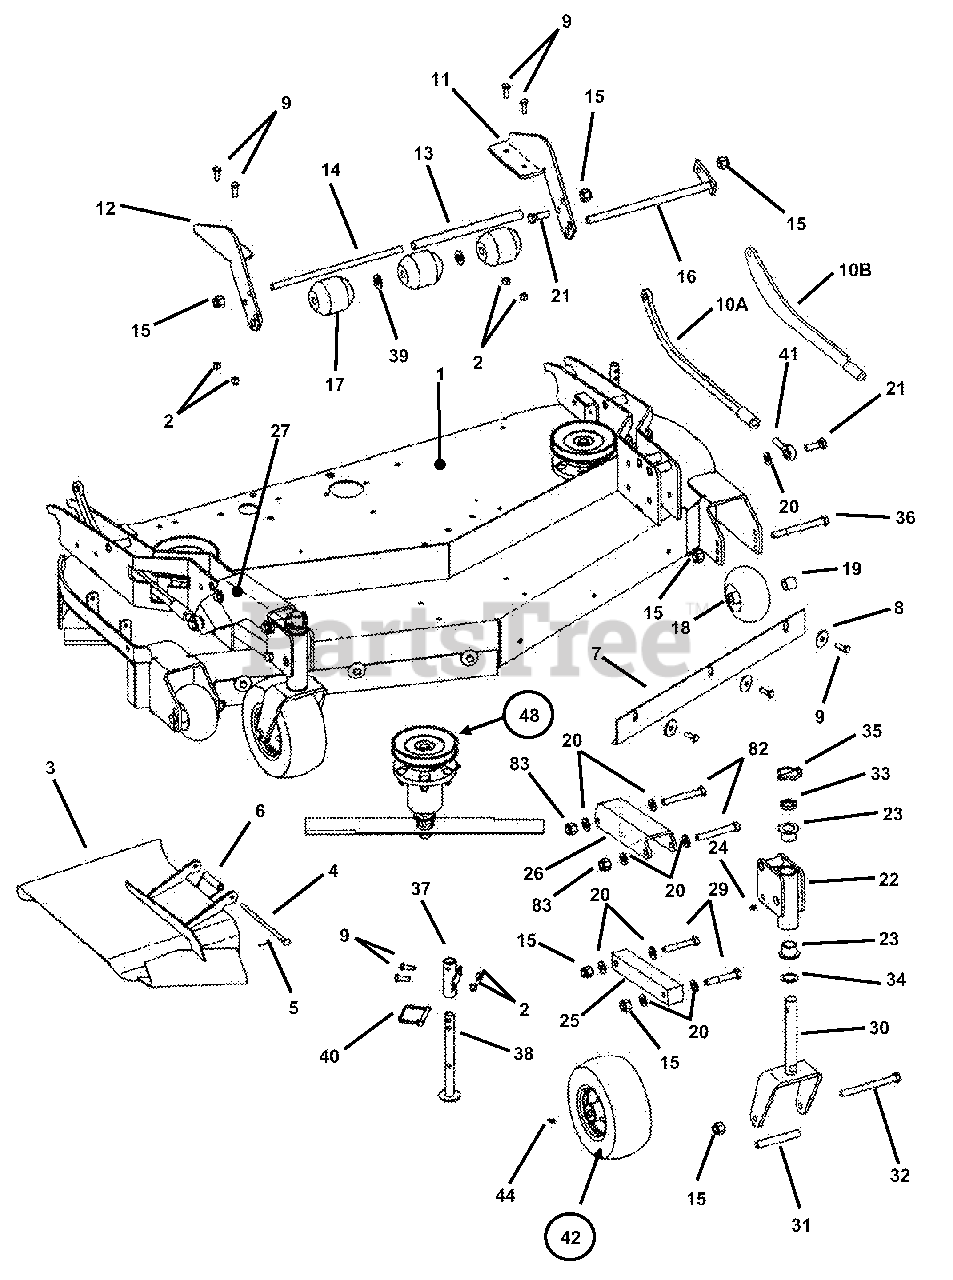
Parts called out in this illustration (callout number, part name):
1	WELDMENT, 52" Deck- Adjustable Height
2	NUT, 3/8-16 HEX NYLON LOCK
3	DEFLECTOR, Chute 52"
4	PIN, Chute Hinge
5	PIN, 3/32 x 1" Cotter
6	SPRING, Chute
7	BAFFLE, Front
8	WASHER, 13/32 x 1-1/2" Flat
9	BOLT, 3/8-16 X 1" GD5 CZ
10A	LINK, Height of Cut
10B	LINK, Height of Cut, Heavy Duty
11	MOUNT, Roller Left Hand
12	MOUNT, Roller Right Hand
13	TUBE, Roller
14	PIN, Roller
15	NUT, 1/2-13 Hex Nyloc
16	WELDMENT, Shaft
17	ROLLER, Low Density Polyethylene
18	WHEEL, Gage
19	SPACER, Gage Wheel
20	WASHER, 1/2" Flat
21	BOLT, 1/2-13 X 1-1/2 GD5 CZ
22	TUBE, Caster (Weldment)
23	BUSHING, Caster
24	FITTING, Lube 1/4-28 Straight
25	ARM, Lower Caster
26	ARM, Caster Support Left Hand
27	ARM, Caster Support Right Hand
28	BOLT, 1/2-13 x 3-3/4" Hex Head Cap, Grade 5
29	BOLT, 1/2-13 X 3" GD5 CZ
30	WELDMENT, Caster
31	SLEEVE, Axle
32	BOLT, 1/2-13 X 5-1/2" GD5 YZ
33	SPACER, 1" x 1 3/8 x .30" (PM)
34	BUSHING, Machine
35	PIN, 7/16" HD Lynch
36	BOLT, 1/2-13 X 5 GD5 YZ
37	TUBE, Jack Stand (Weldment)
38	WELDMENT, Jack Stand
39	WASHER, 5/8" Flat
40	PIN, 5/16" Lynch
41	BALLJOINT, 1/2-20
42	ASSEMBLY, Wheel/Tire
44	FITTING, Grease 1/4"
48	GROUP, Spindle
82	SCREW, 1/2-20 x 4-1/2" Hex Head Cap, Grade 5
83	NUT, 1/2-20 Hex Nyloc
